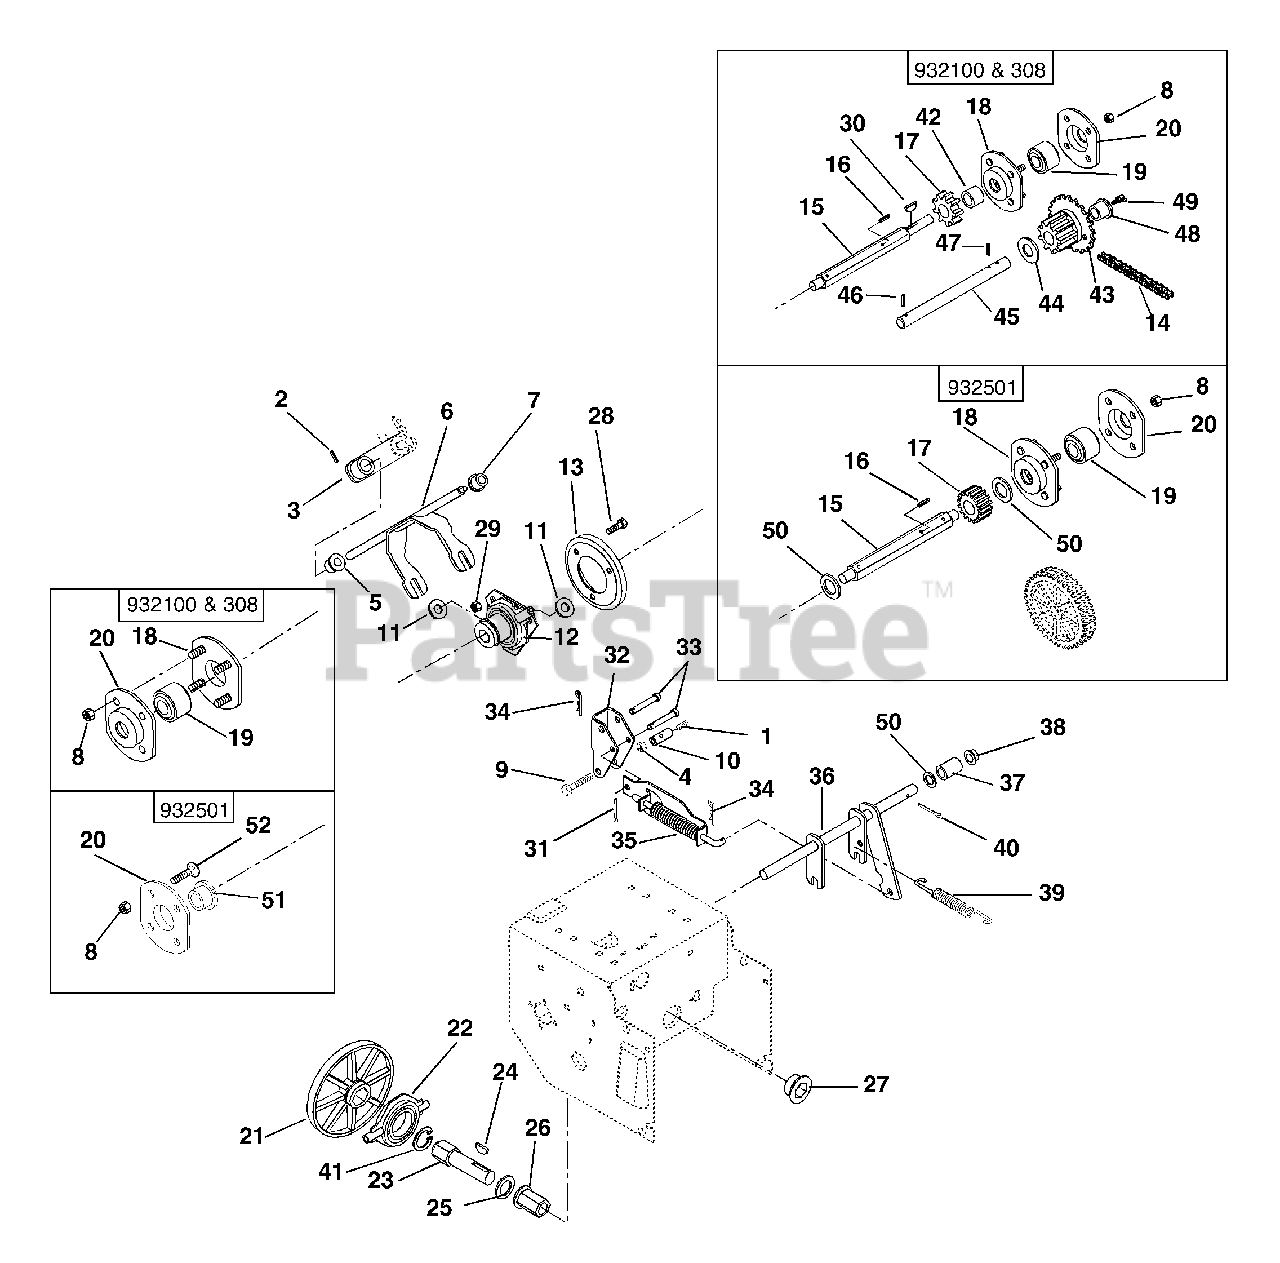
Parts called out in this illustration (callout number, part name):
1	SCR-SET .31-18X.38 SKHCUPDL
2	PIN-ROLL .156X.88
3	ARM, SPEED CONTROL
4	@NUT-LK-CTR .31-18 YWZC
5	BSHG-FLG.500X.625X.312X.750NY
6	FORK-SPEED
7	BSHG-FLG .325X.444X.440X.560
8	NUT-LK-DUAL FACE 10-24 YWZC
9	@BLT-HEX .31-18X.75 GR5 YWZC
10	ROD ADAPTER
11	WSHR-FL-STL .505X1.00X.062YWZC
12	SHIFT CARRIER
13	DISC, FRICTION - 716 MAT'L
14	CHAIN-ROLLER #41X26 PITCHES
15	HEX SHAFT
16	PIN-ROLL .125X.88
17	9 TOOTH SPROCKET
17	PINION
18	BEARING FLANGE
19	BRG-BALL .500X1.38X.437
20	BEARING FLANGE
21	FRICTION PLATE
22	BEARING ASSEMBLY
23	HEX SHAFT
24	KEY-WDRF .188X.75X.313 SAE 9
25	WSHR, THRUST .625X1.125X.063
26	BSHG-FLG .625X.875X1.750X1.188
27	BSHG-FLG .875X1.25X.75X1.50HX
28	@BLT-HEX .25-20X.50 GR5 YWZC
29	@NUT-LK-CTR .25-20 YWZC
30	KEY-WDRF .125X.625X.250 SAE5
31	@PIN-CTR .09X.50 EXTPRSQCT YWZ
32	BRACKET
33	PIN, CLEVIS .243/.248X1.50 YWZ
34	PIN-HAIR INT .08X.18X1.18 YWZC
35	TRACTION CLUTCH ASSEMBLY
35	TRACTION CLUTCH ASSY
36	CLUTCH FORK
37	SPACER .504X.748X.321
38	CAP, .50 ROD YWZC
39	SG-TENS .063X.44X1.56
40	@PIN-CTR .12X1.00 EXTPRSQCT YZ
41	RG-RTNG-EXT 1.250X.050
42	SPACER .513X.748X.620
43	PINION AND SPROCKET ASSY
44	WSHR-FL-STL .630X1.005X.062 YZ
45	SHAFT-PINION
46	PIN-ROLL .125X1.00
47	PIN-ROLL .156X.88
48	BSHG-FLG .625X.750X.500X.875BR
49	DRIVE FITTING, HYD. BRIGHT ZC
50	@WSHR-FL-STL.531X1.06X.095YWZC
51	BSHG-FLG .500X.750X.625X.937
52	BLT-RDHDSQSHK #10-24X.38 GR2YW
